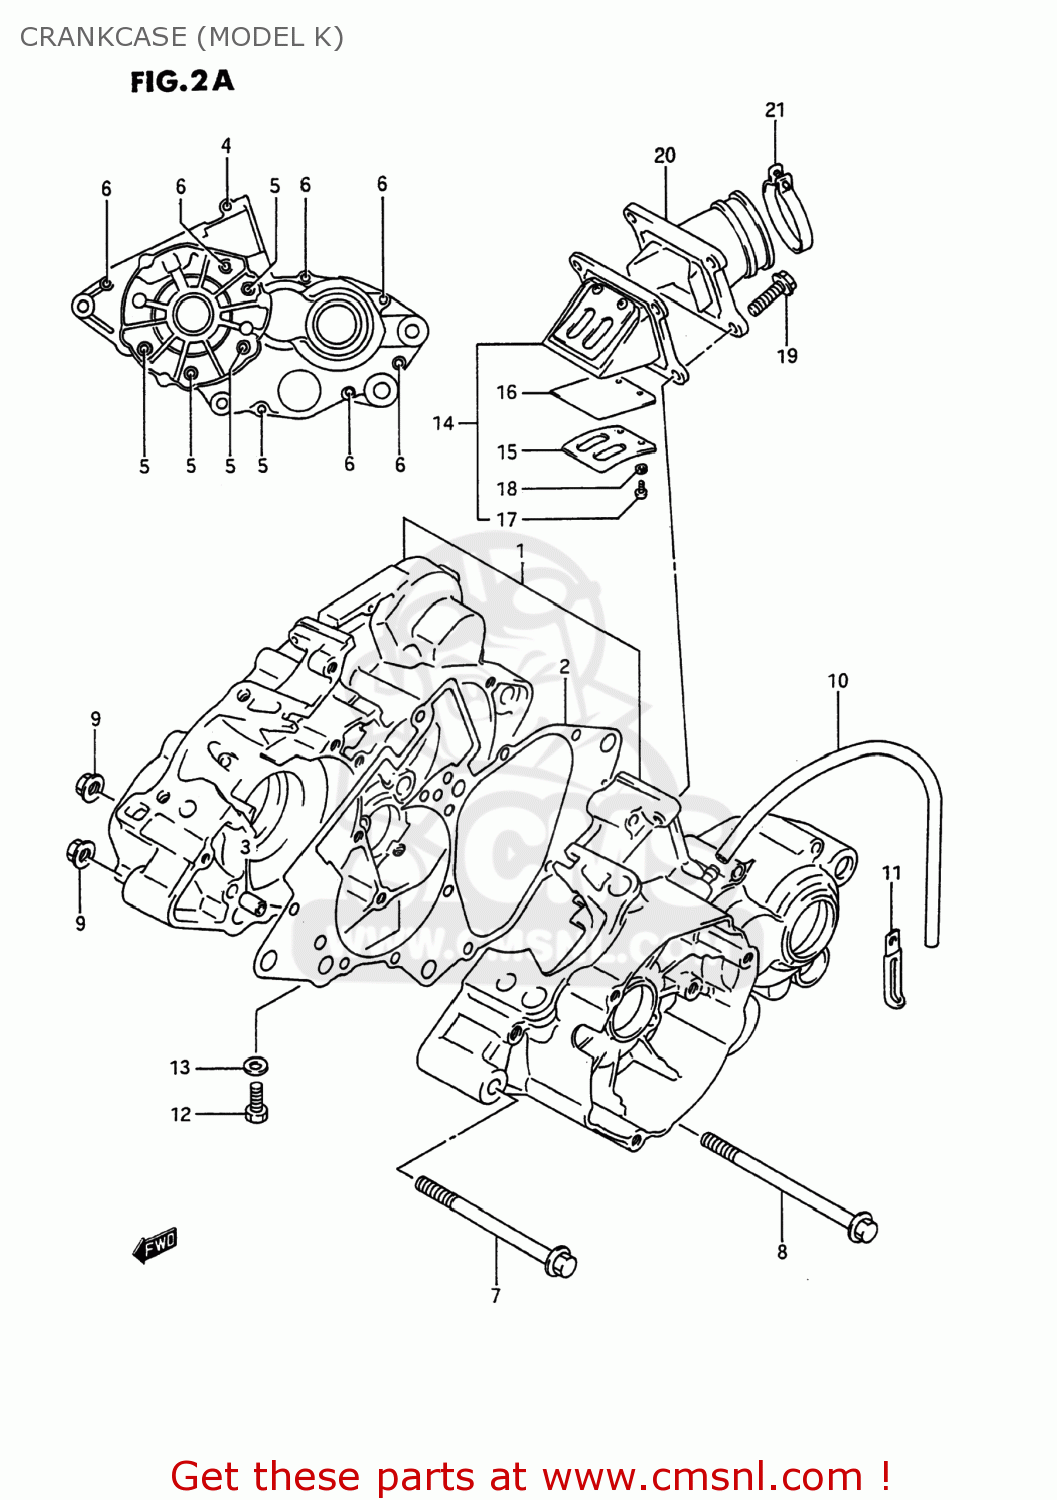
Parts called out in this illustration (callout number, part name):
1	CRANKCASE SET
2	GASKET,CRANKCASE (NAS)
3	PIN
4	BOLT
5	BOLT
6	BOLT
7	BOLT(8X95)
8	BOLT 8X105
9	NUT
10	HOSE(4X7X600)
11	CLAMP
12	BOLT,8X16
13	GASKET 8.2X14X1 (NAS)
14	VALVE ASSEMBLY,REED
15	STOPPER,REED VALVE
16	VALVE,REED
17	SCREW
18	LOCK WASHER
19	BOLT
20	PIPE,INTAKE
21	CLAMP
